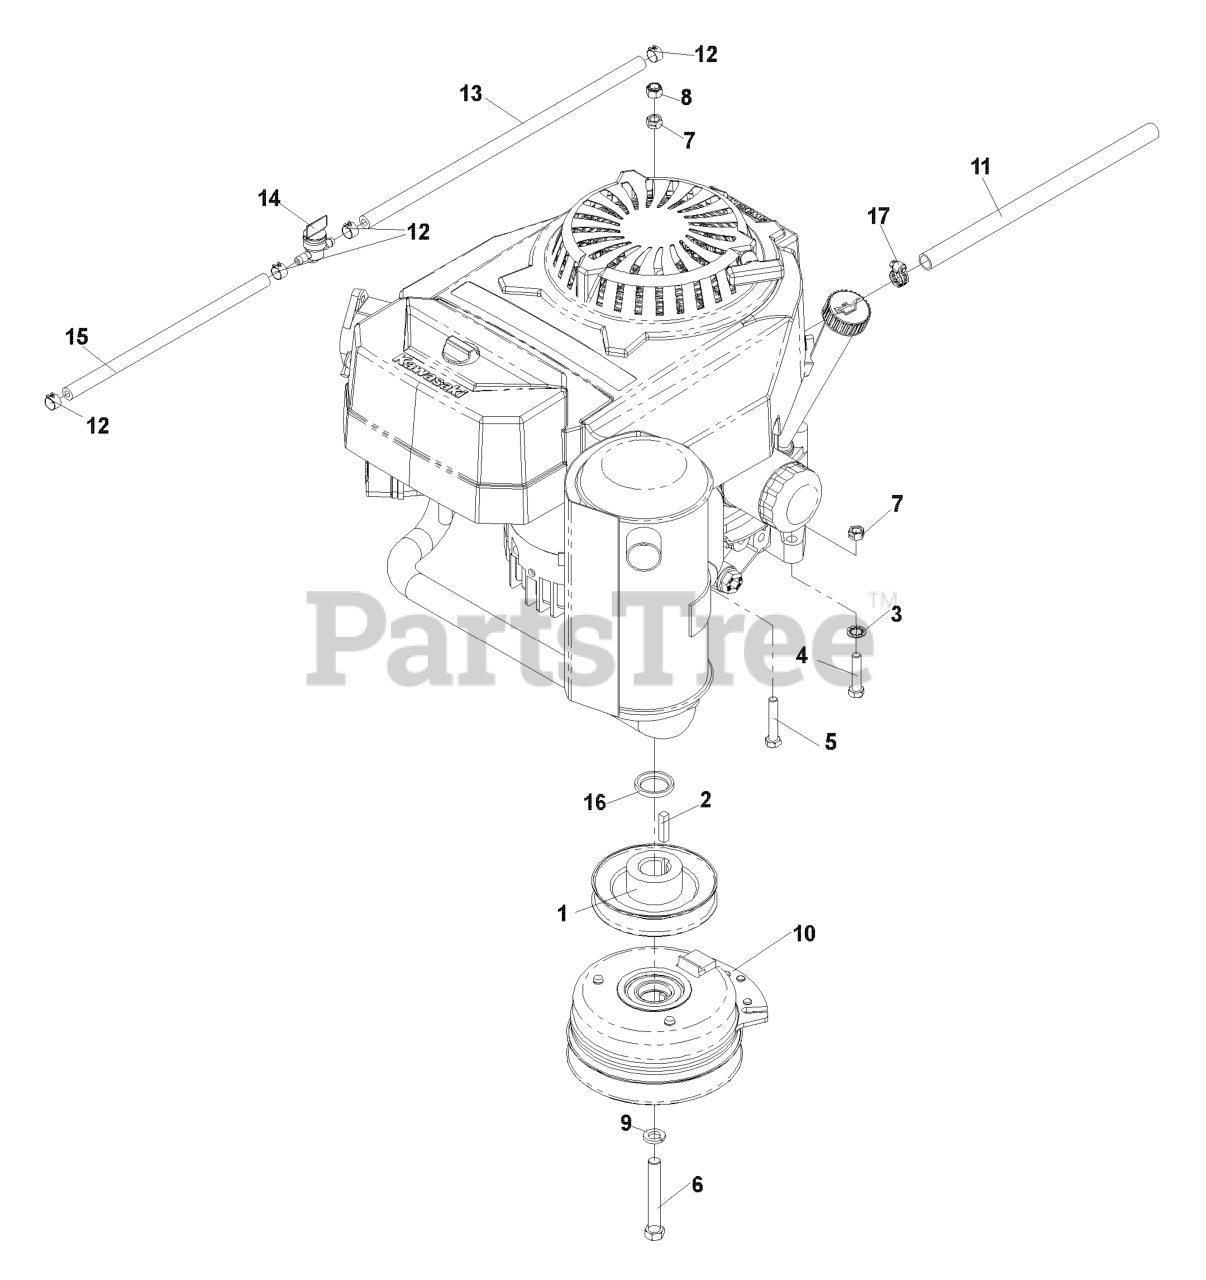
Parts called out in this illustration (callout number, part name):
2	KEY 1/4 SQ X 1 1/8
3	WASHER
4	CAPSCREW 5/16 X 1/1/2 HEX HEAD
5	HCS 5/16C X 1 3/4
6	HEX SCREW 7/16-20 X 3
7	NUT 5/16C CENTERLOCK
8	NUT 5/16 NYLOC
9	WASHER 7/16 LOCK
10	CLUTCH 125 FT/LB
11	OIL DRAIN HOSE
12	HOSE CLAMP
13	FUEL LINE 14"
14	FUEL VALVE
15	GAS LINE 10"
17	HOSE CLAMP T-1865
